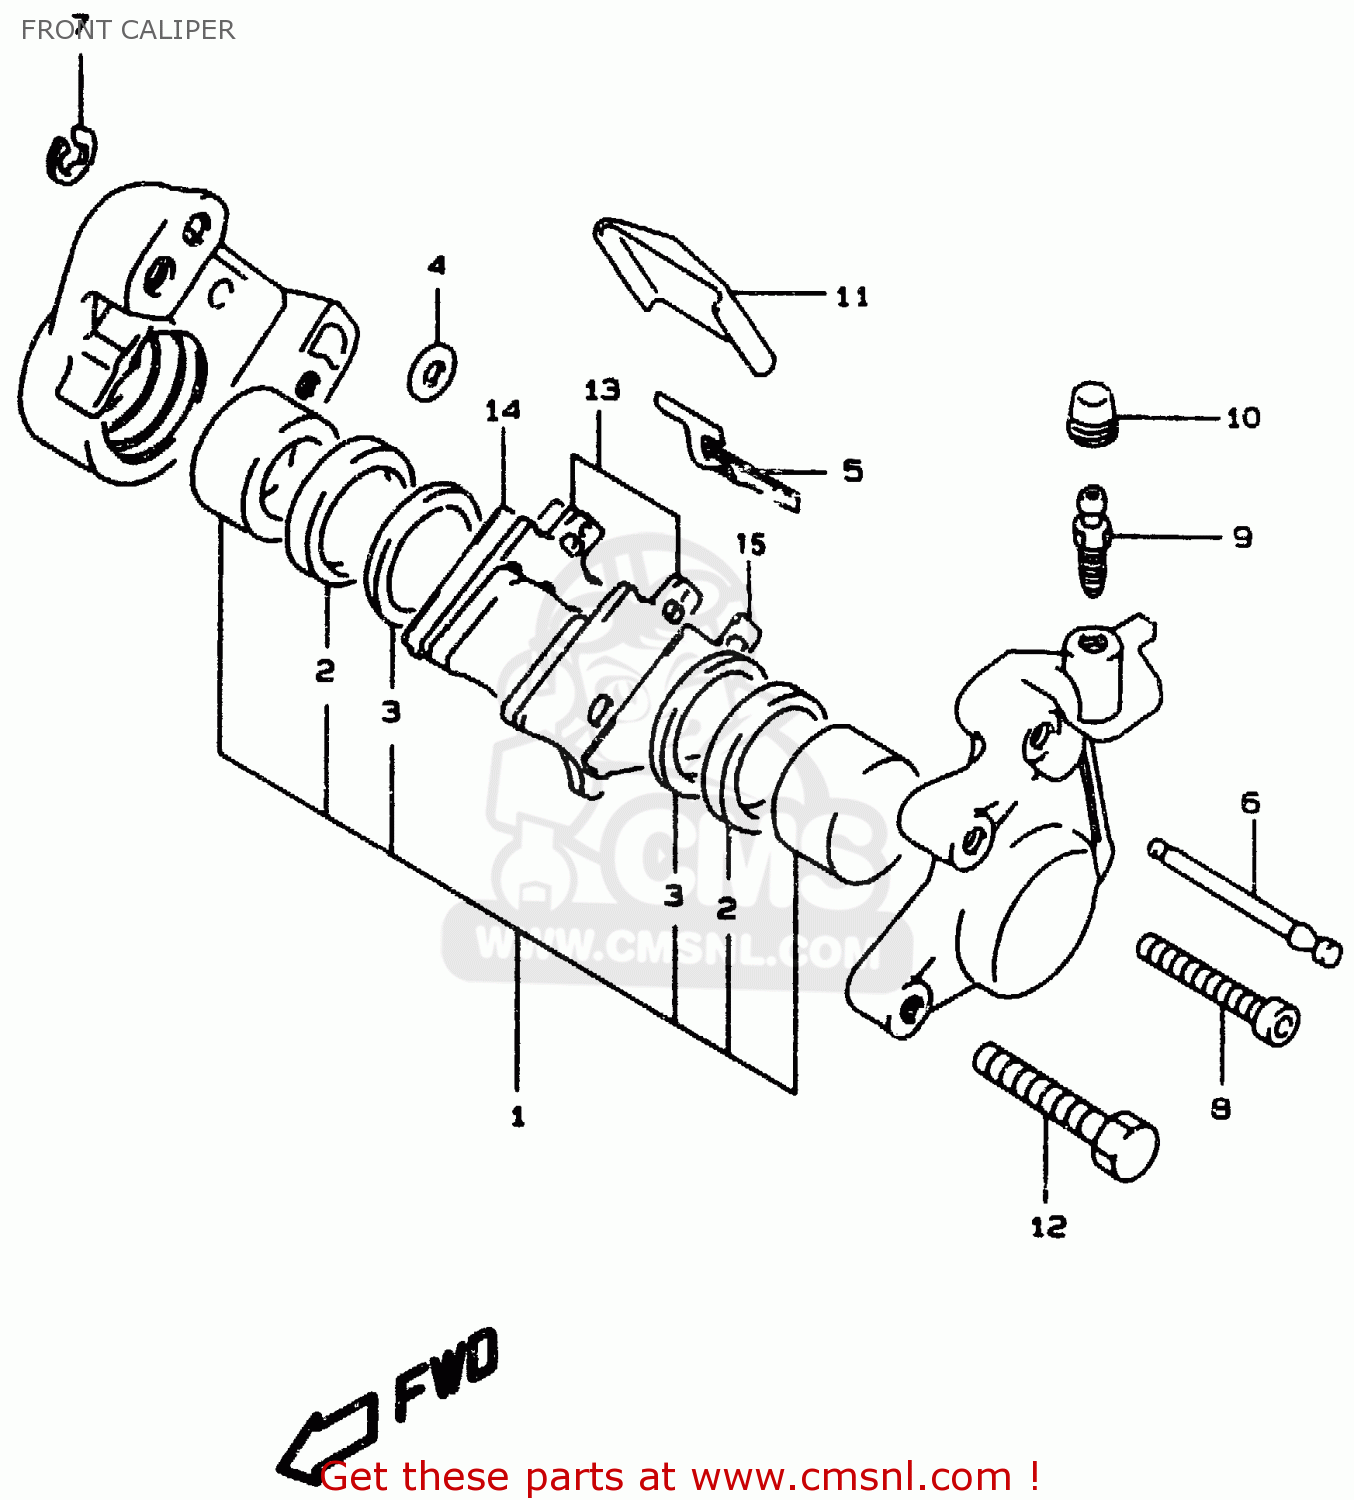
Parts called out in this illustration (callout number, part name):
1	PISTON SET
2	SEAL
3	SEAL
4	SEAL
5	SPRING
6	PIN
7	CIRCLIP
8	BOLT
9	BLEEDER
10	CAP
11	COVER
12	BOLT
13	PAD SET (NAS)
14	SHIM,PAD INNER
15	SHIM,PAD OUTER
